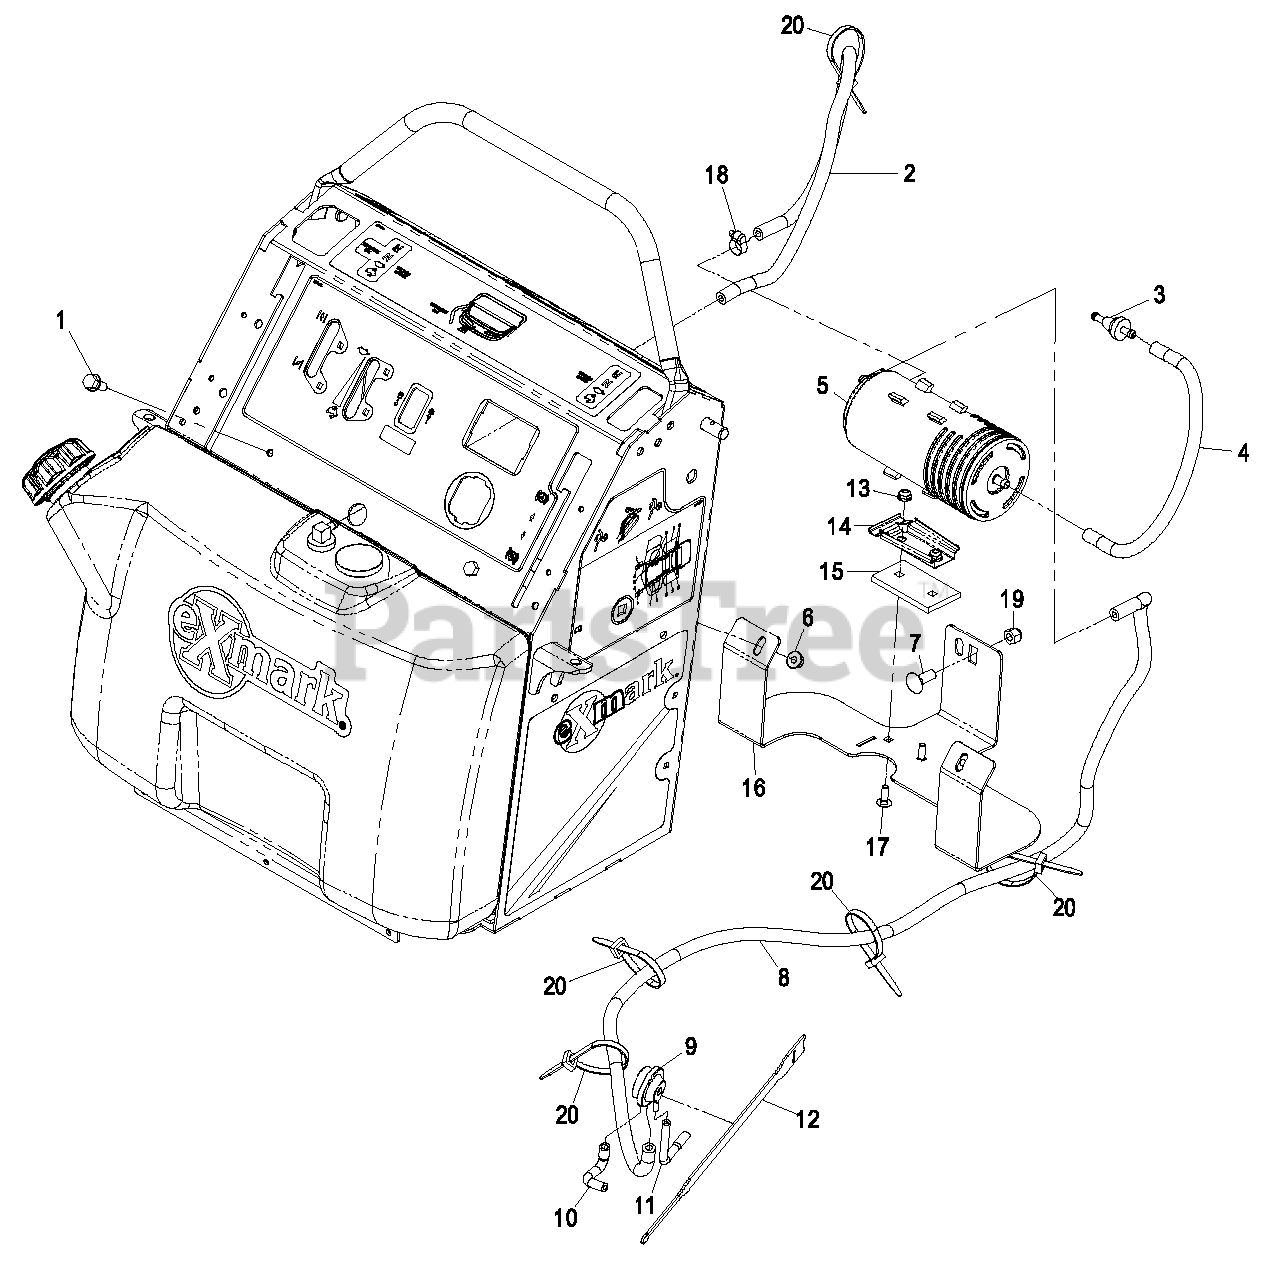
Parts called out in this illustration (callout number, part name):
1	SCREW-THD ROLL, HWH
2	HOSE-FUEL
3	FILTER-FUEL
4	HOSE-FUEL
5	CANISTER-CARBON, 800CC
6	NUT-HF, NI
7	BOLT-CARR
8	HOSE-FUEL
9	VALVE-CONTROL, VACUUM
10	HOSE-VENT, FORMED
11	HOSE-VENT, FORMED
12	STRAP-VELCRO, CABLE TIE
14	BRACKET-CANISTER, CARBON
15	PLATE-CANISTER, CARBON
16	TANK-SUPPORT
17	BOLT-CARR
18	CLAMP-WORM
19	NUT-LOCK, NI
20	TIE-CABLE
